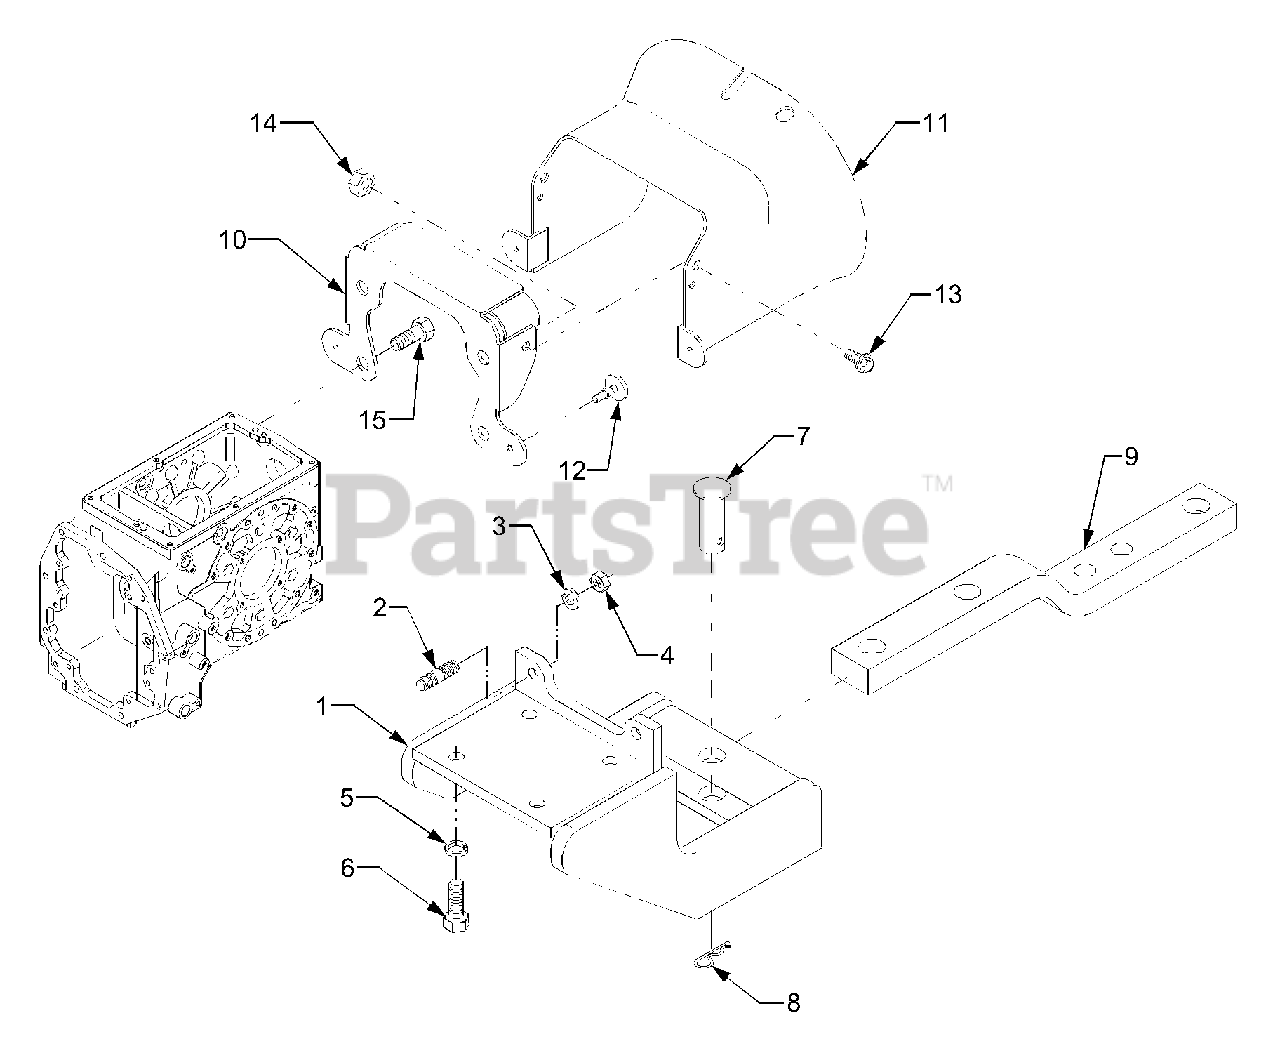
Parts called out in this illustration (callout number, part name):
1	Frame, Swing Drawbar
3	Washer, Spring
5	Spring Washer
9	Drawbar
10	Bracket(Pto Shield)
